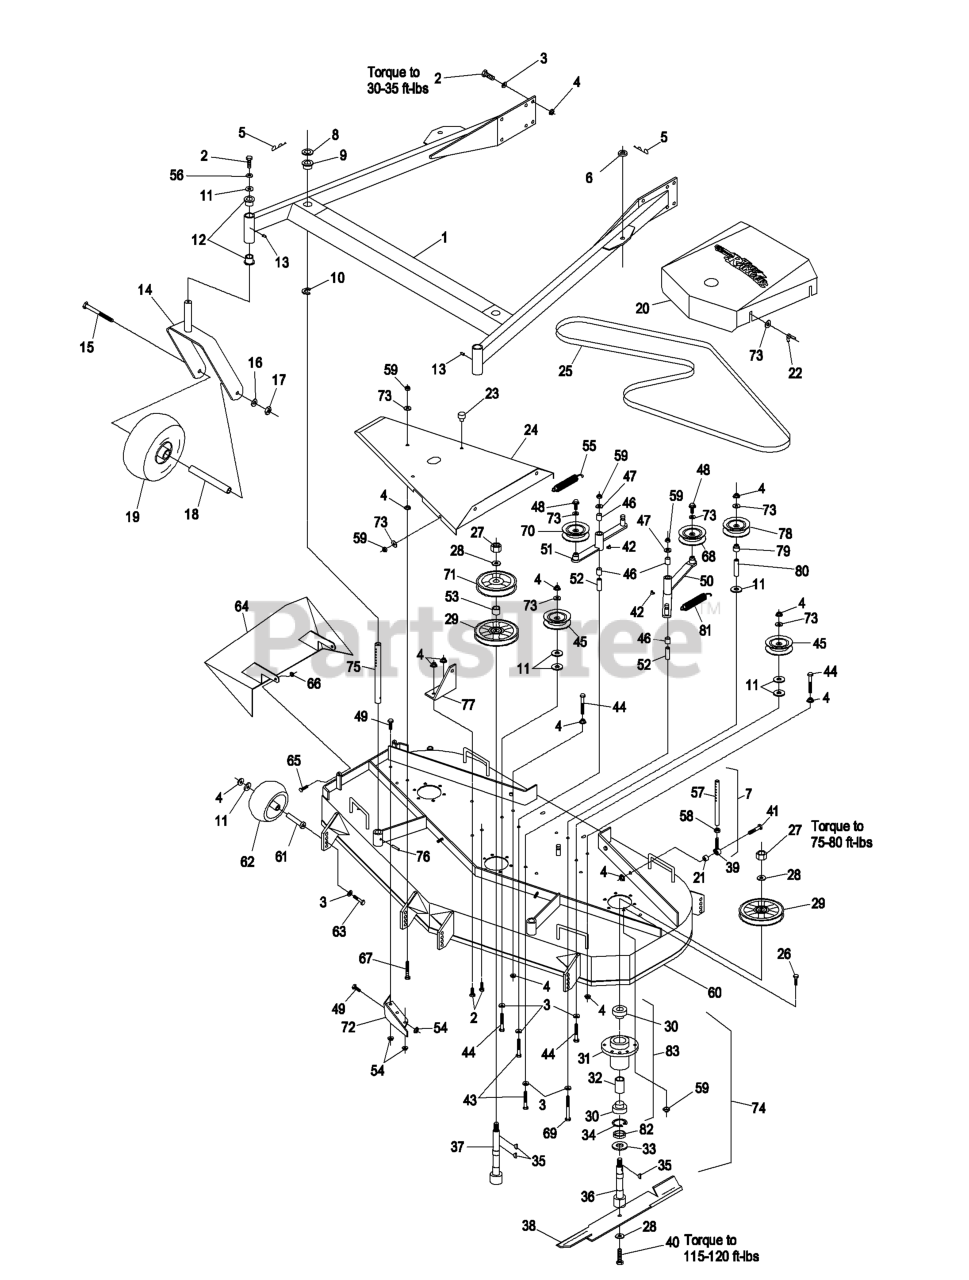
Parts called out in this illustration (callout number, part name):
1	SUPPORT ASSY-FMD60
2	SCREW-HH
3	WASHER-BELLEVILLE
4	NUT-HHF, WHIZ
5	Hairpin, .177
8	SPACER-DECK SUPPORT
9	BUSHING-DECK
10	RING-RETAINING
11	WASHER
12	BEARING-FLANGED
13	FITTING-GREASE
15	SCREW-HH
16	WASHER-LOCK
17	NUT-HH
22	NUT-WING
24	WLD,DECK COVER
25	BELT-DRIVE, BLADE
26	SCREW-HH
27	NUT-HEX
28	WASHER-SPRING
29	SHEAVE,BLADE DRIVE
30	BEARING
32	SPACER-BEARING
33	GUARD-BEARING, BOTTOM
34	RING-SNAP
35	KEY-WOODRUFF
36	SHAFT,SPINDLE SHORT
39	BALLJOINT
40	SCREW-CAP
41	SCREW-HH
42	FITTING-GREASE, 90 DEG
43	SCREW-HH
44	SCREW-HH
45	IDLER,PULLEY
46	SLEEVE-BEARING
47	WASHER-FLAT
48	Bolt, Whizlock 3/8-16 X 1
49	SCREW-HH
50	Arm, Deck Drive Idler
52	BUSHING-PIVOT, IDLER
53	SPACER-TUBE
55	SPRING-EXTENSION
56	WASHER-LOCK
57	LINK,SUPPORT
58	NUT-HEX
59	NUT-LOCK, NI
61	BUSHING-ROLLER
62	ROLLER-SCALP, ANTI
63	SCREW-HH
65	SCREW-HH
66	NUT-LOCK, NI
68	PULLEY-IDLER
69	SCREW-HH
70	IDLER,PULLEY
72	WLD,BAFFLE DISCHARGE
73	NUT-HEX
74	CUTTER HOUSING ASM,OUTER
75	ROD,DECK SUPPORT
77	BRACKET,SPRING ANCHOR
78	PULLEY-IDLER
79	BUSHING,IDLER
80	SPACER-FENDER
81	SPRING-EXTENSION
82	SPACER-PULLEY/BEARING
